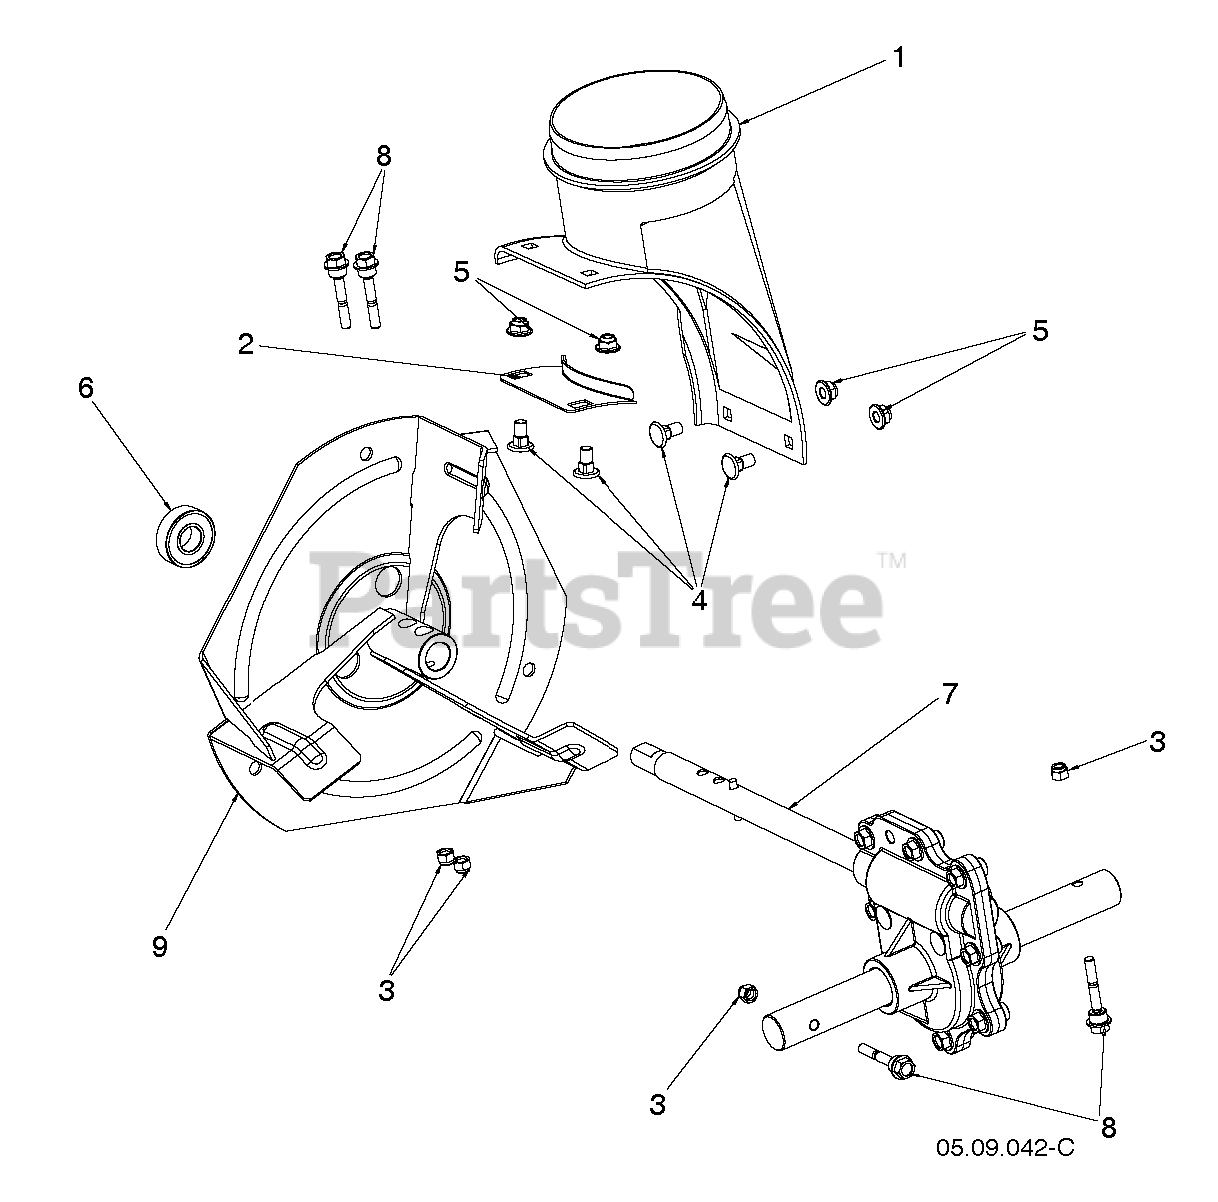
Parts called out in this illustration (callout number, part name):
1	CHUTE.DISCHARGE.BASE
3	NUT HEXAGON 1/4-20 ST ZPB
4	BOLT CARR WAFER BLK 5_16-18 X
5	NUT HEX FLG NYLOCK BLK 5_16-1
8	BOLT SHEAR HX HD 1/4-20 CLEAR
9	IMPELLER.STEEL.SNOW.BLACK
